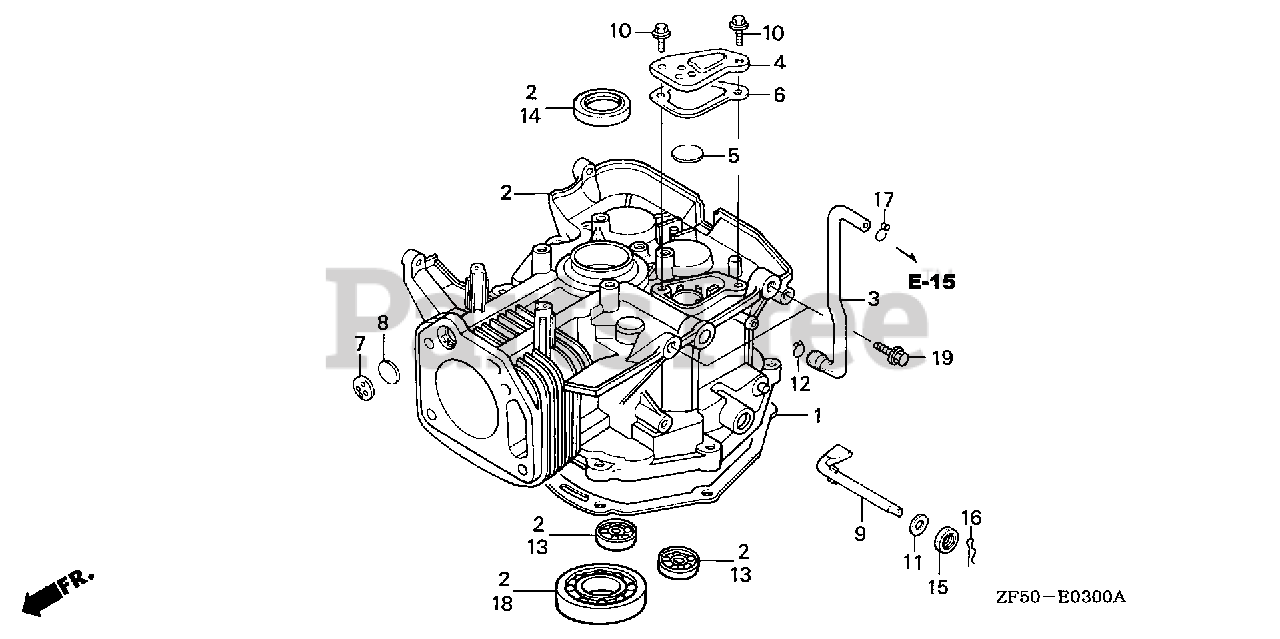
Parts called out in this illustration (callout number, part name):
1	GASKET, OIL PAN
2	CYLINDER ASSY.
3	TUBE, BREATHER
4	CAP, BREATHER CHAMBER
5	VALVE, BREATHER
6	GASKET, BREATHER CAP
9	SHAFT, GOVERNOR ARM
10	BOLT, FLANGE (6X12) (CT200)
11	WASHER, THRUST (8.1MM)
13	BEARING, RADIAL BALL (6202)
14	OIL SEAL (35X52X8)
15	OIL SEAL (8X14X5)
16	PIN, LOCK (8MM)
16	PIN, LOCK (10MM)
17	CLIP, TUBE (C11)
18	BEARING, RADIAL BALL (6207)
